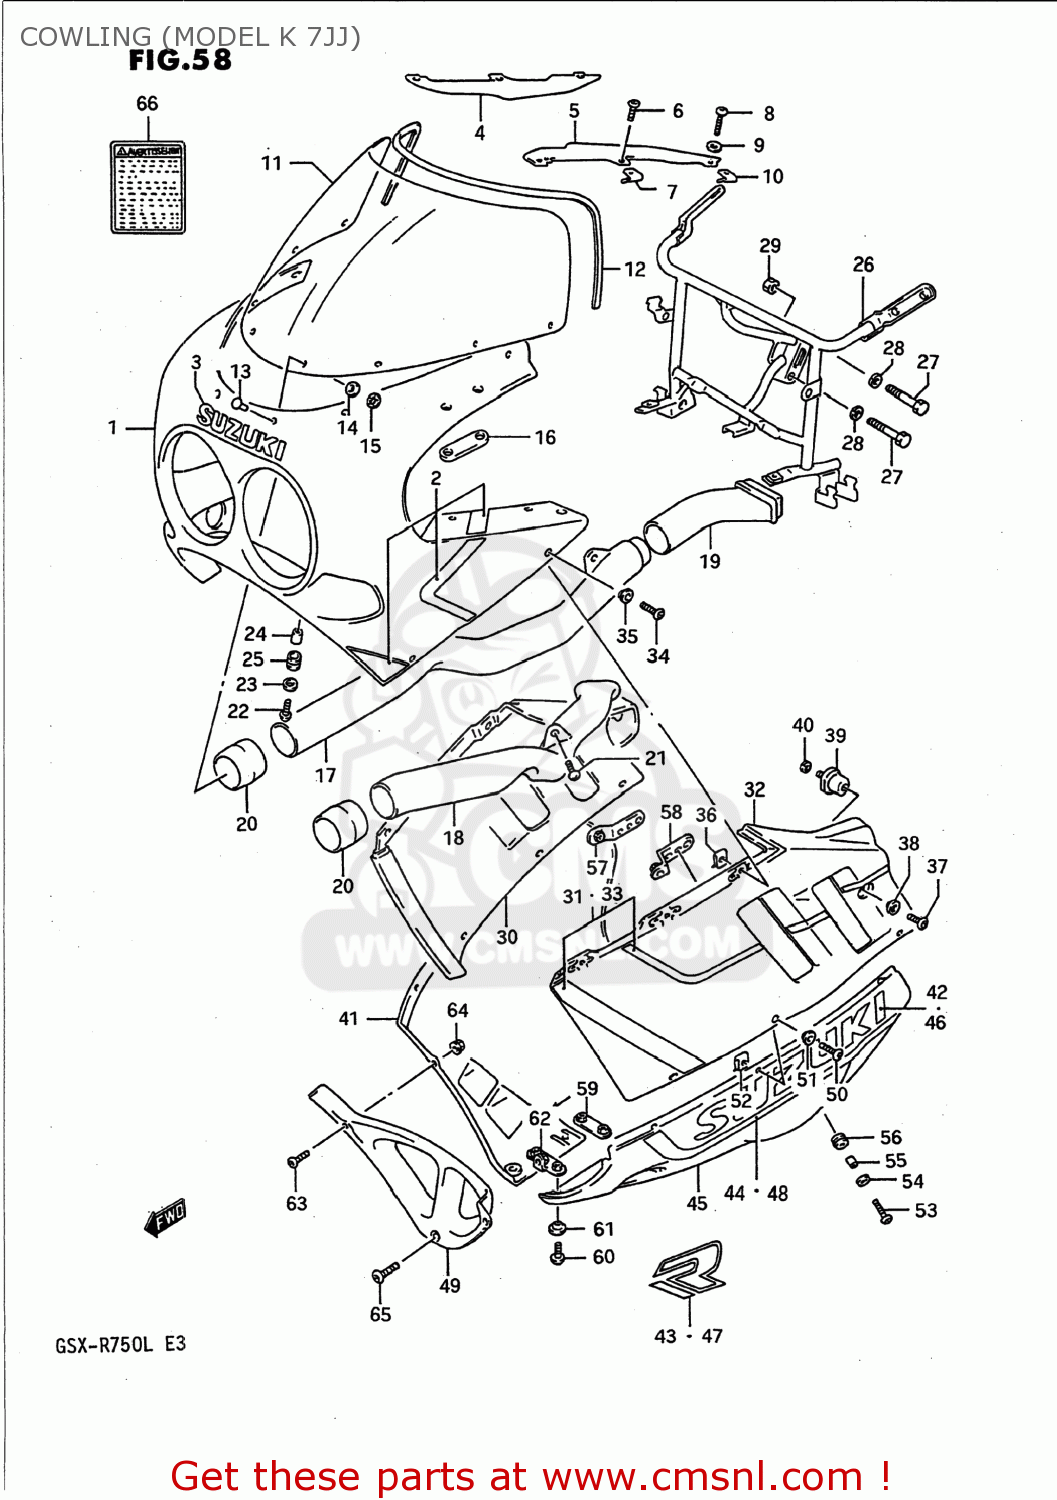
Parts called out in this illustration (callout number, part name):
1	BODY ASSEMBLY,COWLING
2	TAPE SET,COWLING,UPPER
3	EMBLEM,COWLING,UPPER (W)
4	PANEL,COWLING UPPER,RIGHT
5	COVER,COWLING,LEFT
6	SCREW(5X10)
7	NUT
8	SCREW(5X14)
9	WASHER(5.2X11X1)
10	NUT
11	WINDSCREEN
12	MOLDING,WINDSCREEN
13	PIN,WINDSCREEN
14	CUSHION
15	NUT
16	CUSHION,RR VIEW MIRRORR
17	PIPE,AIR INTAKE,FRONT
18	PIPE,AIR INTAKE,FRONT
19	PIPE,AIR INTAKE RR,R
20	JOINT,AIR INTAKE
21	SCREW
22	SCREW(6X20)
23	WASHER(6.5X18X1)
24	SPACER
25	CUSHION
26	BRACE,COWLING
27	BOLT
28	WASHER,LOCK,8.
29	NUT ,8MM
30	COVER,COWLING SIDE,RIGHT
31	TAPE SET,COWLING SIDE
32	COVER,COWLING SIDE,LEFT
33	TAPE SET,COWLING SIDE
34	SCREW(5X18)
35	WASHER(5.2X14X1.5)
36	NUT,HEADLAMP HOUSING,UPPER
37	SCREW(6X12)
38	WASHER(6.3X16X1.5)
39	CUSHION,COWLING
40	WASHER,LOCK
41	COWLING,UNDER,RIGHT
42	EMBLEM,COWLING SIDE (RED)
43	EMBLEM,COWLING,UNDER
44	TAPE,COWLING,UNDER,RIGHT
45	COWLING,UNDER,LEFT
46	EMBLEM,COWLING,UNDER (R)
47	EMBLEM,COWLING,UNDER
48	TAPE,COWLING,UNDER,LEFT
49	COWLING,UNDER,CENTER
50	SCREW(5X18)
51	WASHER(5.2X14X1.5)
52	NUT,HEADLAMP HOUSING,UPPER
53	SCREW(6X20)
54	WASHER(6.5X18X1)
55	SPACER
56	CUSHION
57	BRACKET
58	BRACE,COWLING UNDER,LH
59	BRACE,COWLING LWR COVER RR
60	SCREW(6X16)
61	WASHER(6.3X16X1.5)
62	BRACE,COWLING LWR COVER
63	SCREW(5X14)
64	NUT
65	SCREW(6X16)
66	LABEL (WARNING SCREEN)
